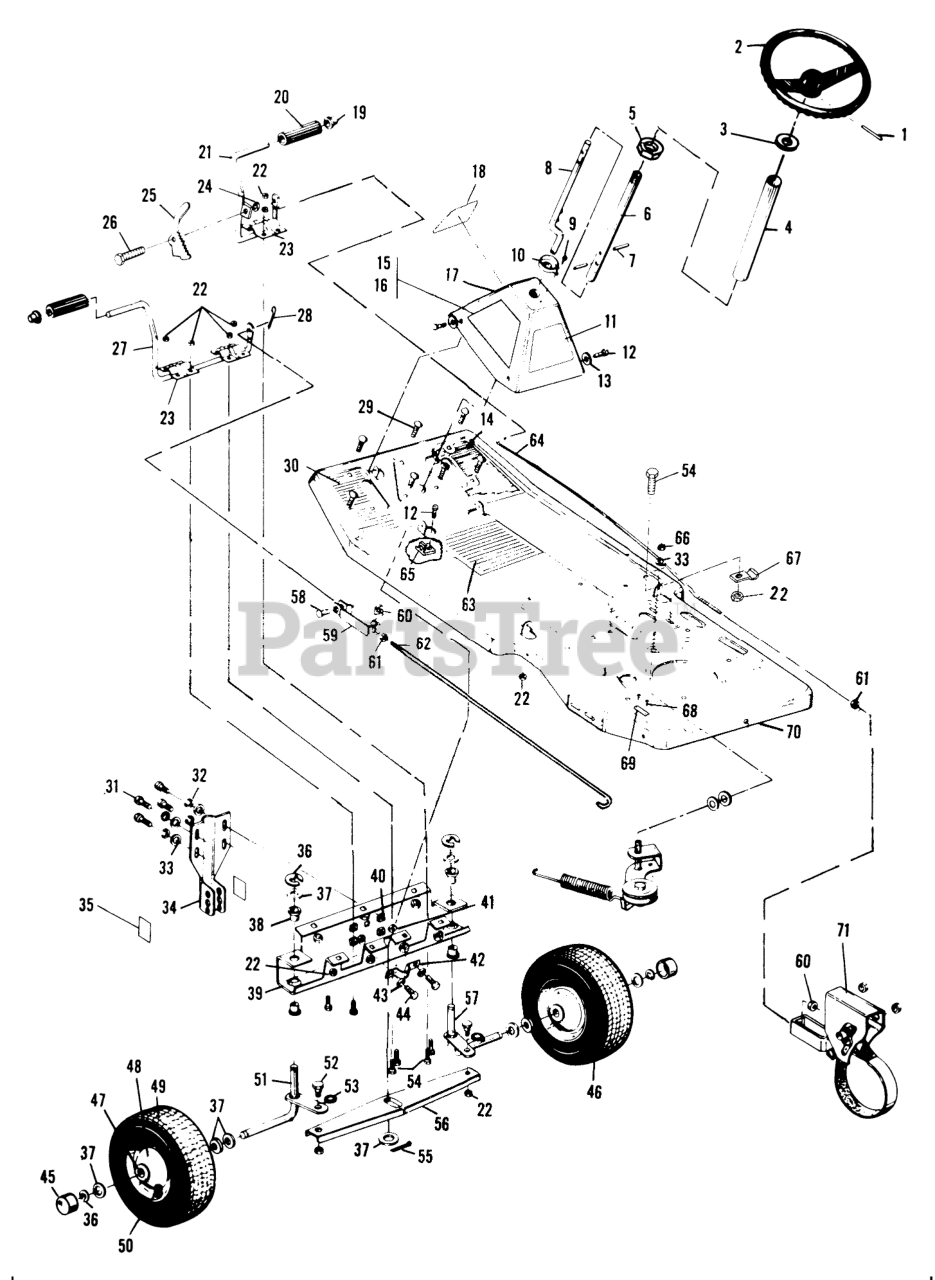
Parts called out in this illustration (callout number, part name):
1	Roll Pin
2	Steering Wheel
3	Washer, Plastic
4	Housing, Steering Tube
5	Nut, Speed
6	Tube, Steering
7	Pin, Spiral
8	Shaft, Steering
9	Screw, No.10-32 x 1/2 In.
10	Bushing, Steering Tube
11	DecaI, Instruction
12	Screw, Taptite, 1/4-20 x 5/8 In.
13	Lockwasher
14	Pad, Footrest, Right
15	Decal, Console, R.H .
16	Decal, Console, L.H.
17	Quadrant
18	Decal, Console, Front
19	Speed Nut, Push
20	Pad, PedaI
21	Arm, Brake Pedal
22	Nut-Nylok
23	Bracket, Pedal Rod
24	Nut-Nylok
25	Latch, Parking Brake
26	Shoulder Bolt
27	Arm, Clutch Pedal
28	Cotter Pin, 3/32 x 3/4 In.
29	Carriage Bolt, 5/16-18 x 5/8 In.
30	Pad, Footrest, Left
31	Bolt Hex. 3/8-16 x 1
32	Lockwasher, Split, 3/8 In.
33	Washer
34	Bracket, Deck Hanger
35	Decal, Deck Hanger
36	"E" Ring
37	Flatwasher, 5/8 In.
38	Bushing, Spindle
39	Bracket, Front Axle
40	Nut, Speed Grip, 3/8-16 Thd
41	Nut, Speed Grip, 5/16-18 Thd
42	"U" Bracket
43	Washer-Lock
44	Screw, Hex Hd, 5/16-18 x 3/4 In.
45	Hub Cap
46	Wheel & Tire Assy, Front, Complete Includes Items 43, 44, 45 & 46
47	Bushing
48	Wheel with Bearings
49	Tire, 4.10-3.50 x 4
50	Valve Stem
51	Spindle, Steering Left
52	Shoulder Bolt
53	Washer, Spring
54	Screw, Hex Hd, 5/16-18 x 5/8 In.
55	Cotter Pin, 3/16 x 1 1/4 In.
56	Link, Steering
57	Spindle, Steering Right
58	Pin, Clevis
59	Clevis
60	Nut, Square, 1/4-20 Thd
61	Nut, Hex, 1/4-20 Thd
62	Rod, Clutch
63	Pad, Footrest Center
64	Rod, Brake
65	Clip, Reinforcement
66	Nut
67	Bracket, Rod Support
68	Drive Screw, No. 6 x 5/16 In.
69	Plate, Model Number
70	Main Frame
71	Brake, Assembly, Complete
72	Tag, Warranty (Not Illustr.)
